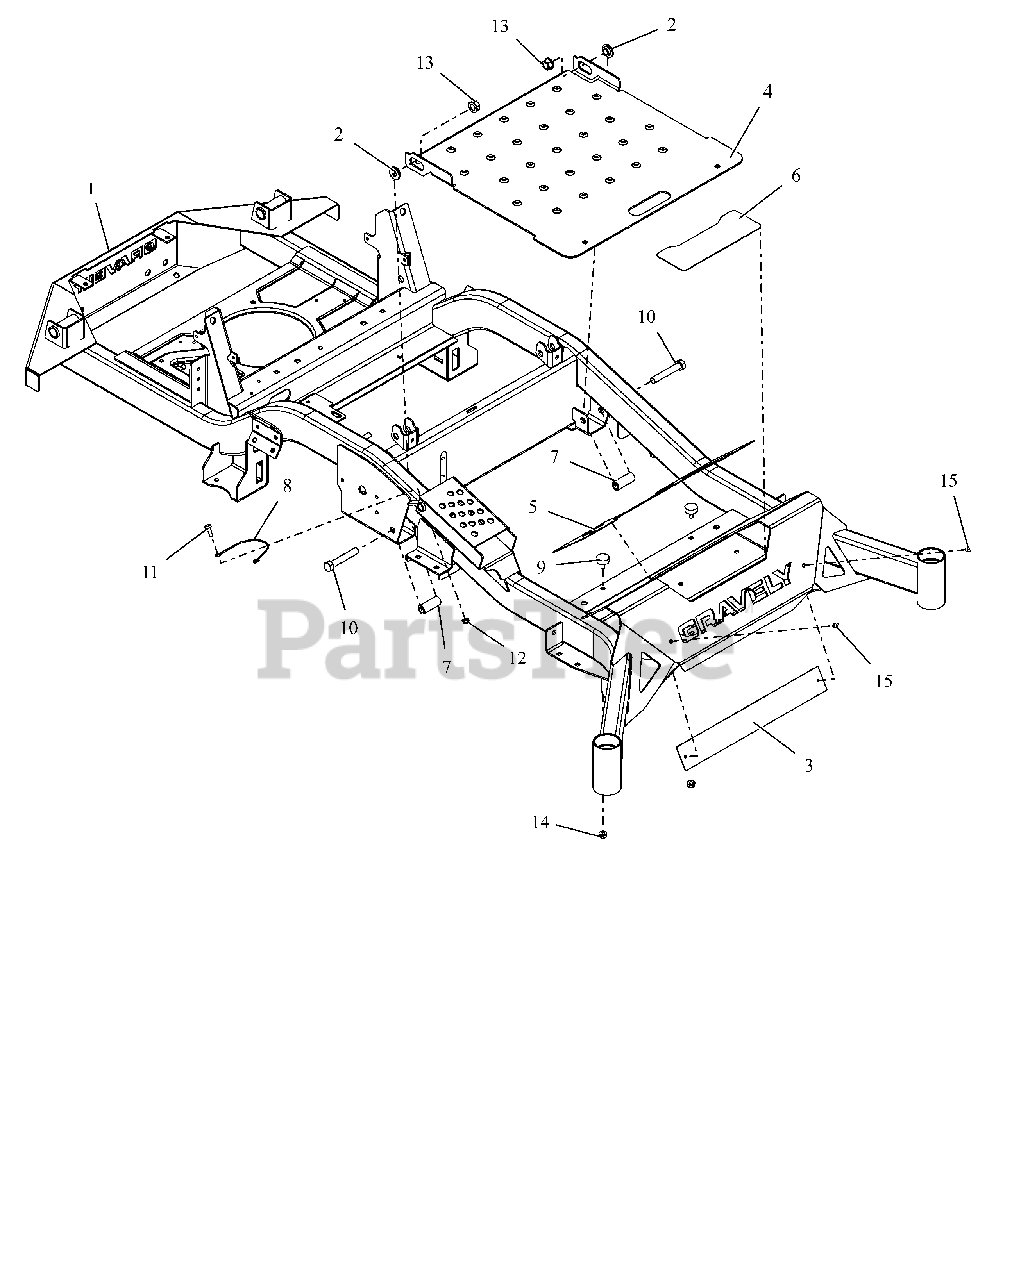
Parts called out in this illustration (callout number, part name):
1	HD 60"FRAME W/SAFETY DECALS
2	BSHG-FLG .515X.750X.310X1.120
3	PLATE, BACK FOOT-REST XL
4	KIT,ACCESS PANEL W/DECALS-RED
5	GRIP, FRONT
6	GRIP, STEP
7	SPACER, .515X.75X1.83
8	CABLE, 12.0 LANYARD, NYLON
9	BUMPER, RUBBER
10	BLT, HEX .50-13X3.00 G5 ZCC
11	BLT, HEX .25-20X.75 G5 ZCC
12	NUT,NYL-FLG .25-20 GF ZCC
13	NUT-LK-TOP-FLG .500-13 GF ZCC
14	NUT,SPNLK-FLG .31-18 G5 ZCC
15	RIVET, .1875 AL/AL .126-.250
